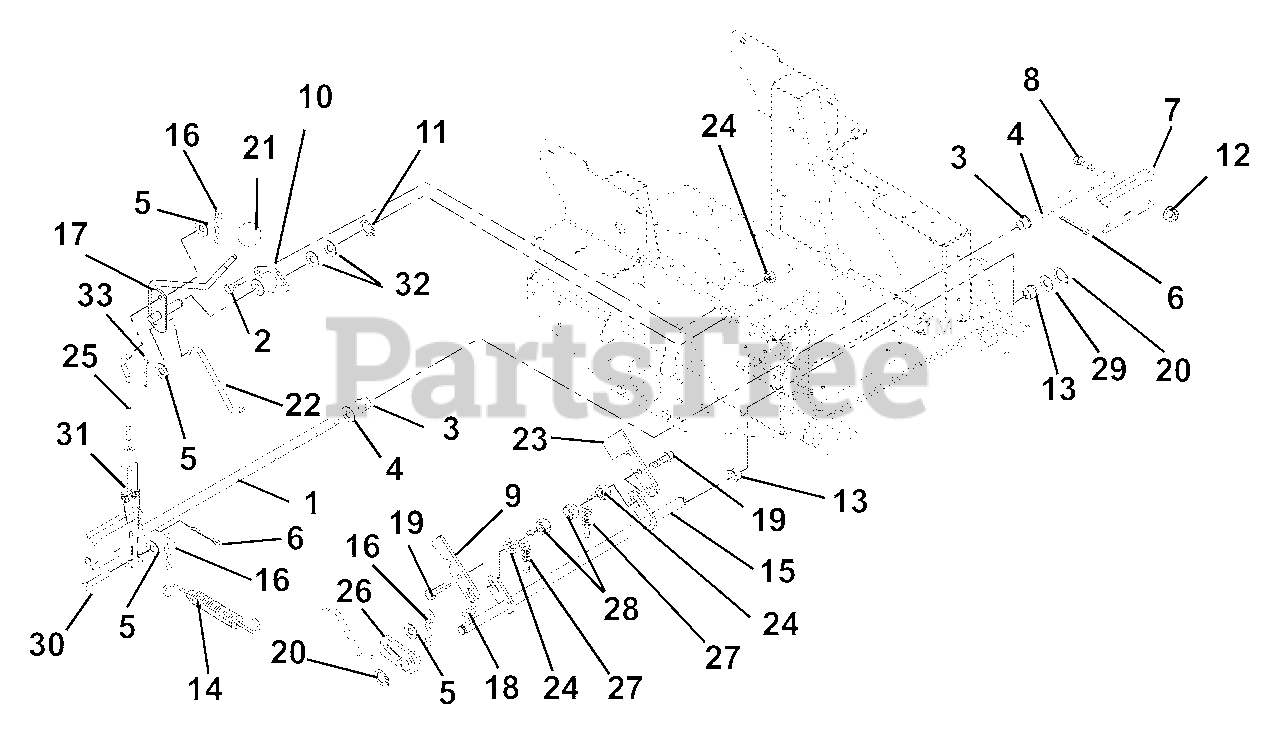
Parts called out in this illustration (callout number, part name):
1	Weldment, Brake Shaft
2	Bolt, Hex .31-18 x .75 Grade 5
3	Bushing, Flange .762 x 1.00 x .58 x 1.48 Nylon
4	Washer, Flat Steel .755 x 1.375 x .062
5	Washer, Flat Steel .406 x .812 x .065
6	Pin, Cotter .12 x 1.00 Extended Prong Square Cut
7	Paddle, Brake
8	Bolt, Hex .25-20 x 1.25 Grade 5
9	Slide, Interlocking Brake
10	Bushing, Flange
11	Ring, Retaining External .625 x .05
12	Nut, Locking Top Flange .25-20
13	Bushing, Flange .50 x .75 x .75 x 1.00
14	Spring, Engine Transmission
15	Weldment, Mechanical Brake
16	Pin, Hair
17	Weldment, Brake Actuating
18	Key, Woodruff .13 x .63
19	Bolt, Hex .31-18 x 1.25 Grade 5
20	Ring, Retaining External .50 x .05
21	Knob, Steering Lock
22	Linkage, Brake Actuating
23	Interlock, Safety Switch
24	Nut, Locking Top Flange .31-18
25	Linkage, Brake Compact-Z
26	Weldment, Parking Brake Hub
27	Spring, Tension .061 x .50 x 3.0
28	Nut, Locking Center .31-18
29	Washer, Flat Steel .505 x 1.00 x .062
30	Pin, Clevis .37 x 1.75
31	Clevis,.38-24 Adjustable
32	Washer-Flat-Steel .630 x 1.250 x .062
33	Pin, Cotter .09 x .75 Extended Prong Square Cut
